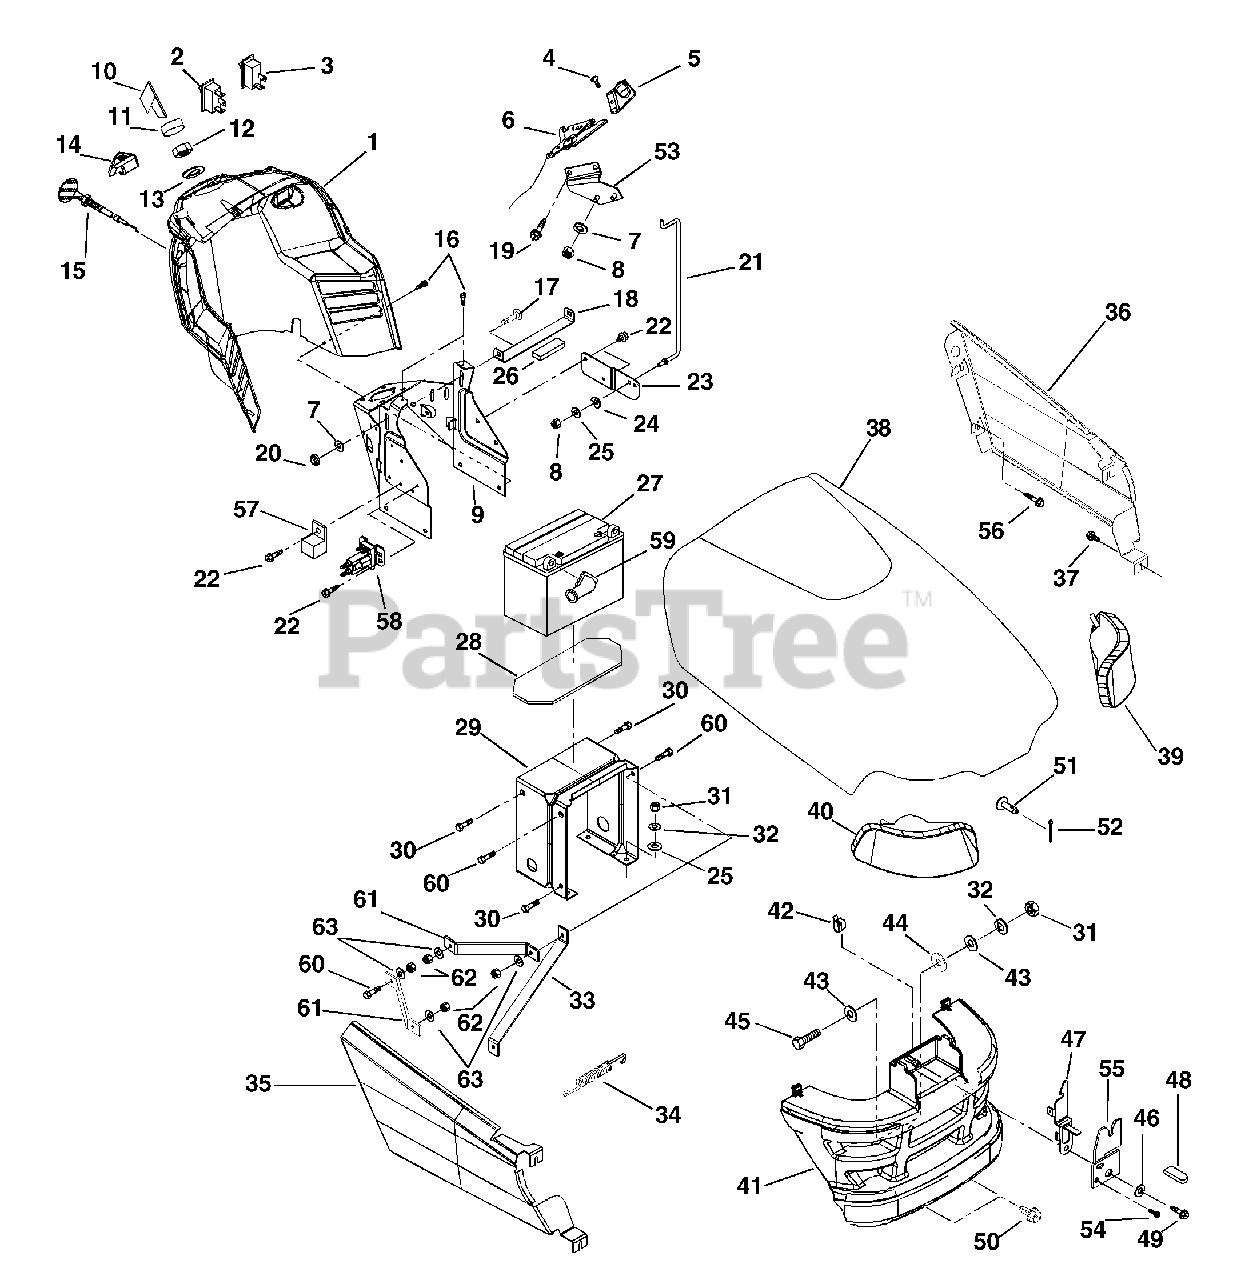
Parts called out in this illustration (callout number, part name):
1	DASH
2	SWITCH - CRUISE
3	SWITCH - LIGHT
4	SCR-SET 10-24X.38 UNC-3A
5	KNOB, THROTTLE
6	CABLE, THROTTLE
7	WSHR-FL-STL .323X.625X.062 YWZ
8	@NUT-LK-CTR .25-20 YWZC
9	SUPPORT, DASH TOP
10	KEY -W/CAP
11	CAP - IGNITION SWITCH
12	NUT- PANEL .562-24 GRECO
13	WSHR-LK-INT .625X.045 YWZC
14	PTO KNOB / SHAFT ASSY.
15	CHOKE CABLE
16	SCR-TAP 10-24X.484 HWH TR
17	@BLT-RDHDSQNK .31-18X.75 G5YZ
18	HOLDD0WN, BATTERY
19	@SCR-TAP .25-20X.37 HWH YWZ TR
20	@NUT-LK-NYL .312-18 YWZC
21	ROD - HOOD PROP
22	@SCR-TAP 10-24X.375 HWH YZ TR
23	MOUNT - PROP ROD
24	WAVE WASHER .390X.655X.110
25	@WSHR-FL-STL.312X.734X.065 YWZ
26	PAD, FOAM
27	BATTERY W/ TUBE
28	RUBBER PAD
29	SUPPORT-DASH BASE
30	SCR-TAP .312-18X.50 HWH TR BL
31	@NUT-HEX .31-18 YWZC
32	WSHR-LK .312X.097 HVY YWZC
34	SG-TENS .035X.45X2.75 WLD 3.5
35	PANEL, R.H
36	PANEL, L.H
37	SCR-TAP 12-16X.500 HI-LOTPHBL
38	HOOD WITH DECALS
39	HEADLIGHT- LH
40	HEADLIGHT- RH
41	GRILLE
42	CLIP-HARNESS TINNERMAN
43	WSHR-FL-STL .328X1.0X.094 YWZC
44	WSHR-FL-NYL .390X1.000X.062
45	@BLT-HEX .31-18X1.00 GR5 YWZC
46	WSHR-FL-STL .281X1.250X.048 BL
47	HOOD LATCH
48	GRIP .062 X .375 X 1.000 RE
49	SCR-TAP 12-24X.50 HWH TR BLACK
50	SCR-TAP .312-18X.50 HWH TR BL
51	PIN, CLEVIS .243/.248X1.50 YWZ
52	@PIN-CTR .09X.75 EXTPRSQCT YWZ
53	BRACE, THROTTLE CONTROL
54	SCR-TAP 10-12X.50 CRPH PL A BL
55	LOCATOR, HOOD
56	SCR-TAP 10-16X.62 SLPH AB YWZC
57	RELAY
58	SOLENOID
59	INSULATOR
60	@BLT-HEX .31-18X.75 GR5 YWZC
61	BRACKET-STEERING ASSEMBLY
62	@NUT-LK-NYL .312-18 YWZC
63	@WSHR-FL-STL.344X.688X.065YWZC
